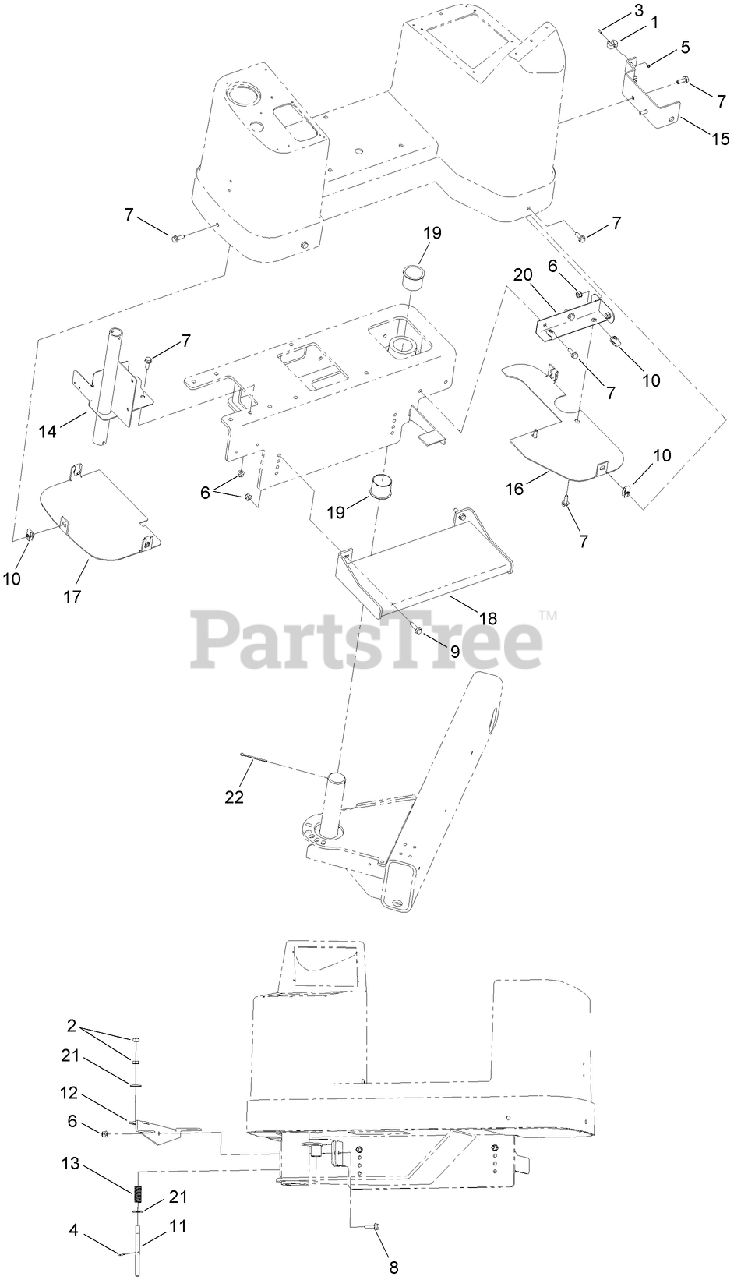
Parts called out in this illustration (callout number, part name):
1	CLIP-SPRING
2	NUT-JAM
3	SCREW-PRH
4	PIN-COTTER
5	NUT-KEPS
6	NUT-LOCK, NI
7	SCREW-HHF
8	SCREW-HHF
9	SCREW-HHF
11	ROD-SWING, SEAT
12	ARM-ADJUSTMENT, SEAT
13	SPRING-PIVOT LOCK, SEAT
14	MOUNT-UMBRELLA
15	PLATE-RETAINING, CORD
16	PLATE-GUARD, SPLASH
17	PLATE-GUARD, SPLASH
19	BEARING-FLANGED
20	SUPPORT-SHROUD, LEFT
21	WASHER-FLAT
22	PIN-COTTER
